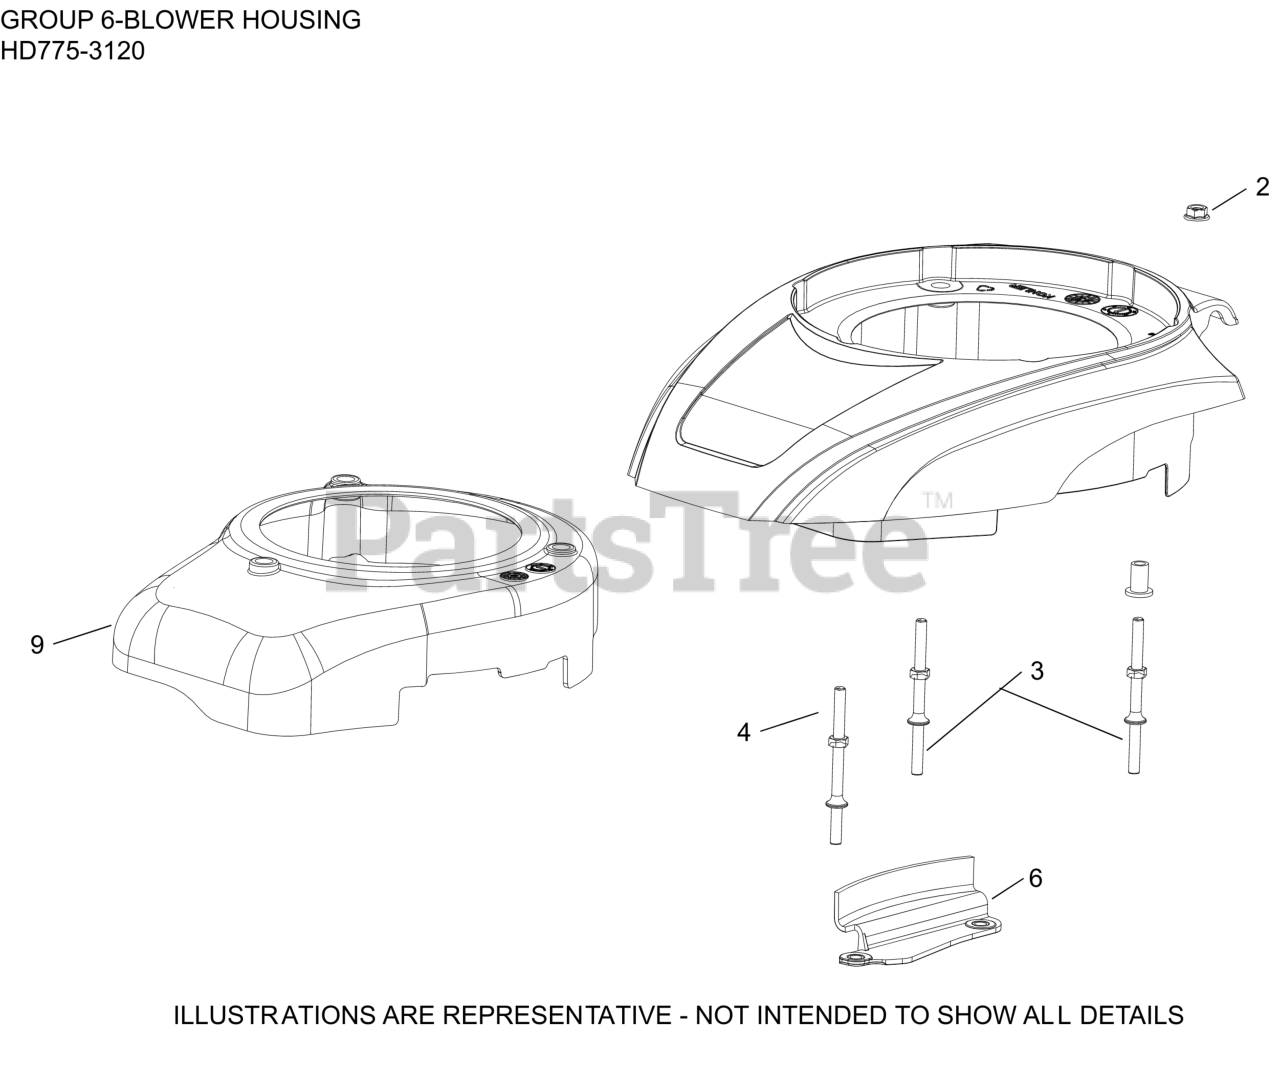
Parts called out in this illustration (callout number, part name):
2	NUT, LOCK M6
3	STUD-USE 14 072 25-S
4	STUD-USE 14 072 26-S
6	GUARD, FINGER
9	HOUSING, BLOWER
